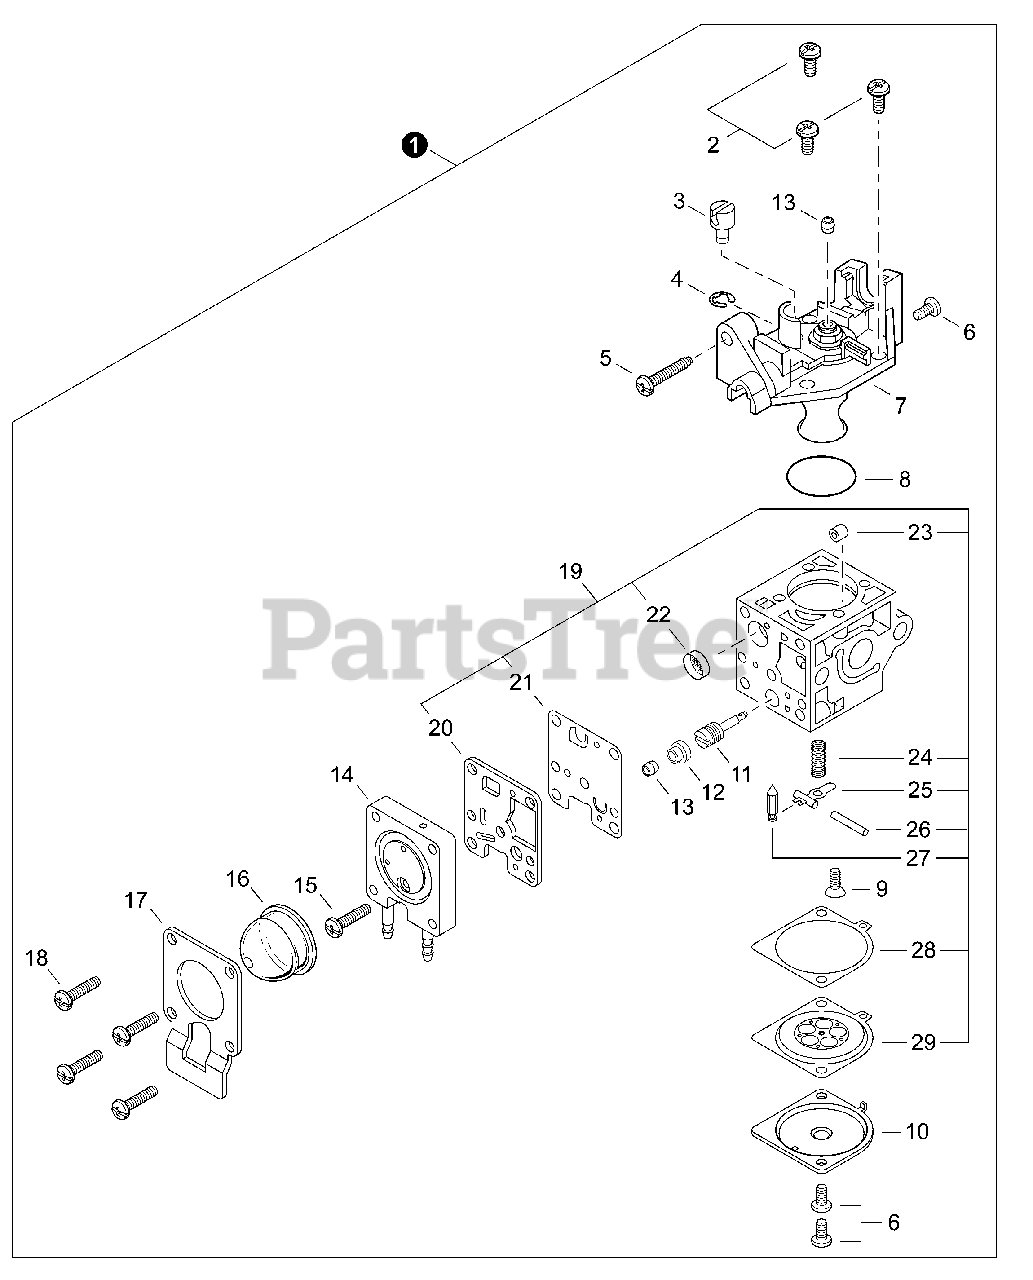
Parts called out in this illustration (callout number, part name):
1	CARBURETOR - RB-K92A
5	SCREW, THROTTLE ADJUST
7	COVER ASSY, ROTOR
10	COVER, METERING DIAPHRAGM
11	NEEDLE, HIGH SPEED
12	CAP, LIMITER
14	BODY ASSY, PURGE
16	BULB, PURGE
17	RETAINER, PURGE BULB
19	REPAIR KIT
20	GASKET, PUMP
21	DIAPHRAGM, PUMP
22	SCREEN, FUEL INLET
23	GUIDE, ROLLER
24	SPRING, METERING LEVER
25	LEVER, METERING
26	PIN, METERING LEVER
27	VALVE, INLET NEEDLE
28	GASKET, METERING DIAPHRAGM
29	DIAPHRAGM, METERING
